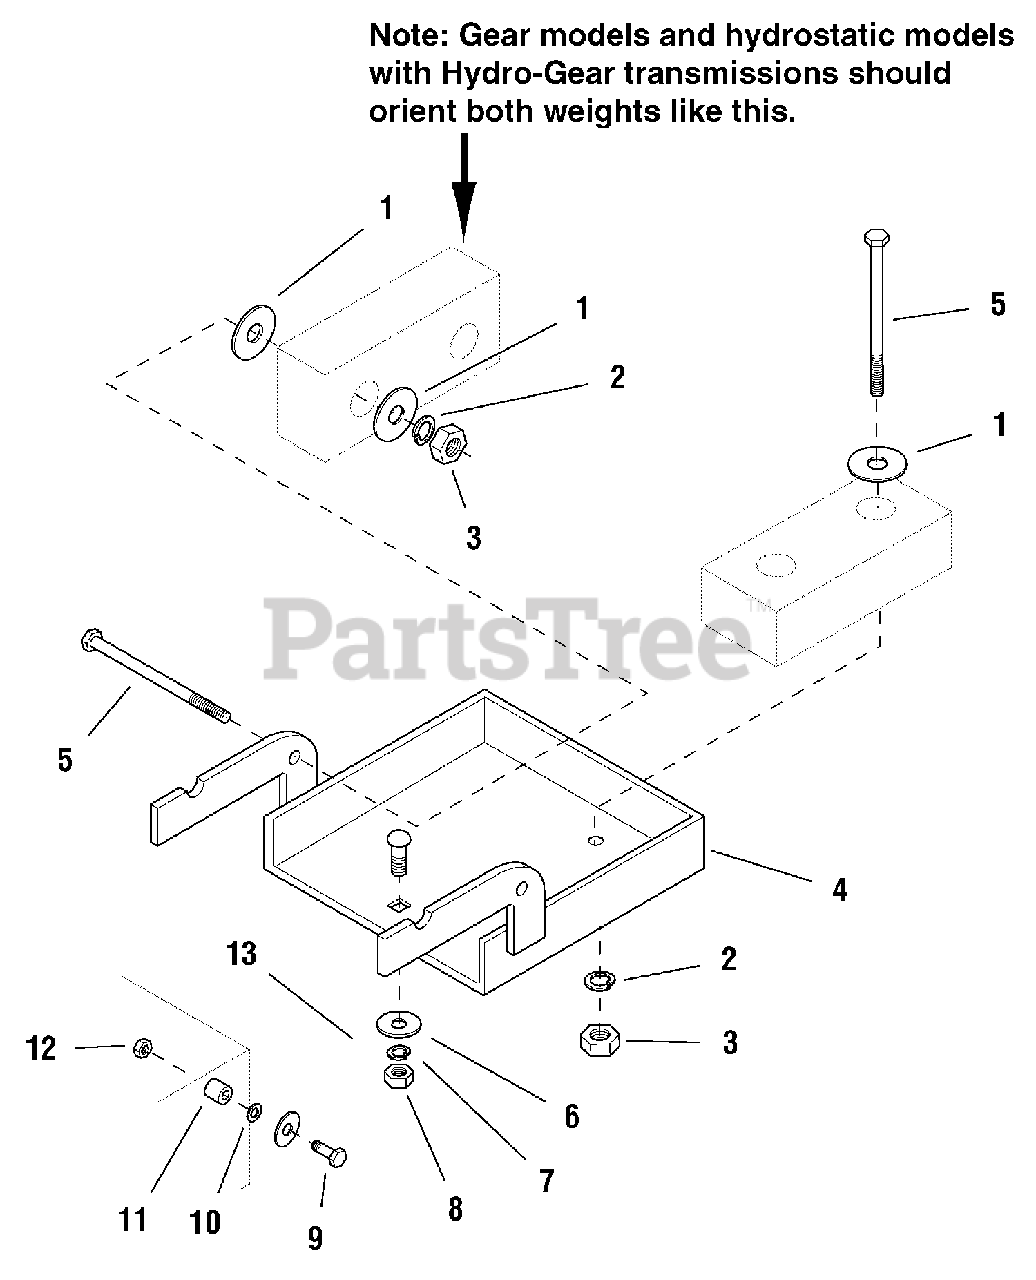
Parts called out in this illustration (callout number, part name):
1	FENDER WASHER, 1/2
2	LOCKWASHER
3	JAM NUT, 7/16-14
4	WEIGHT BOX ASSEMBLY
5	CAPSCREW, 7/16-14 x 4-1/2
6	WASHER, 13/32-1 x 1/8
7	LOCKWASHER, 3/8
8	NUT, 3/8-16
9	CAPSCREW, 3/8-16 x 1-1/4
10	WASHER, 3/8
12	LOCKNUT, 3/8-16
13	CARRIAGE BOLT, 3/8-16 x 1
